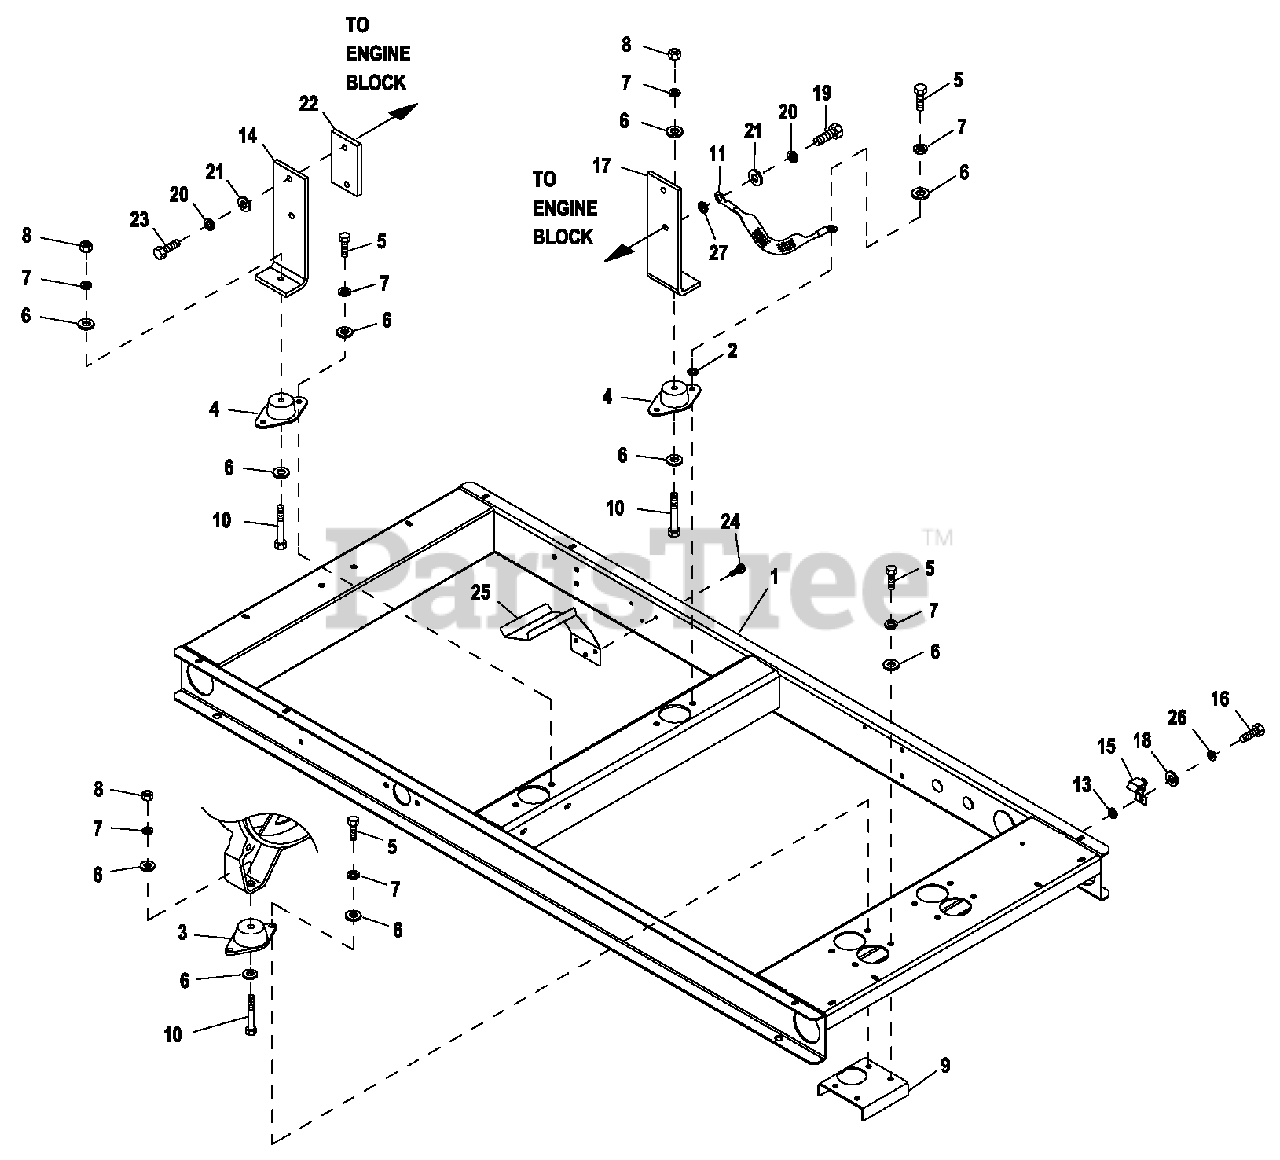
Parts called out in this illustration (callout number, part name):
1	MOUNTING BASE 2.4L
2	WASHER SHAKEPROOF EXT 5/16 STL
3	DAMPENER VIBRATION
4	VIB. ISO. 70-75 DURO
5	SCREW HHC M8-1.25 X 20 G8.8
6	WASHER FLAT 5/16 ZINC
7	WASHER LOCK M8-5/16
8	NUT HEX M8-1.25 G8 YEL CHR
9	ALTERNATOR SUPPORT BLOCK OFF
10	SCREW HHC M8-1.25 X 60 G8.8
11	EARTH STRAP
13	WASHER SHAKEPROOF EXT 1/4 STL
14	SUPPORT ENGINE LEFT SIDE
15	LUG SLDLSS #2-#8 X 17/64 CU
16	SCREW HHC M6-1.0X1 6 G8.8
17	SUPPORT ENGINE RIGHT SIDE
18	WASHER FLAT 1/4-M6 ZINC
19	SCREW HHC M10-1.25 X 30 C8.8
20	WASHER LOCKM10
21	WASHER FLAT 3/8-M10 ZINC
22	SPACER LH ENGINE MOUNT
23	SCREW HHC M10-1.25 X 40 C8.8
24	SCREW HWHT M6-1 X 16 N WA Z/JS
25	HEAT SHIELD 2.4L G2
26	WASHER LOCK M6-1/4
27	WASHER LOCK EXT 7/16 STL
